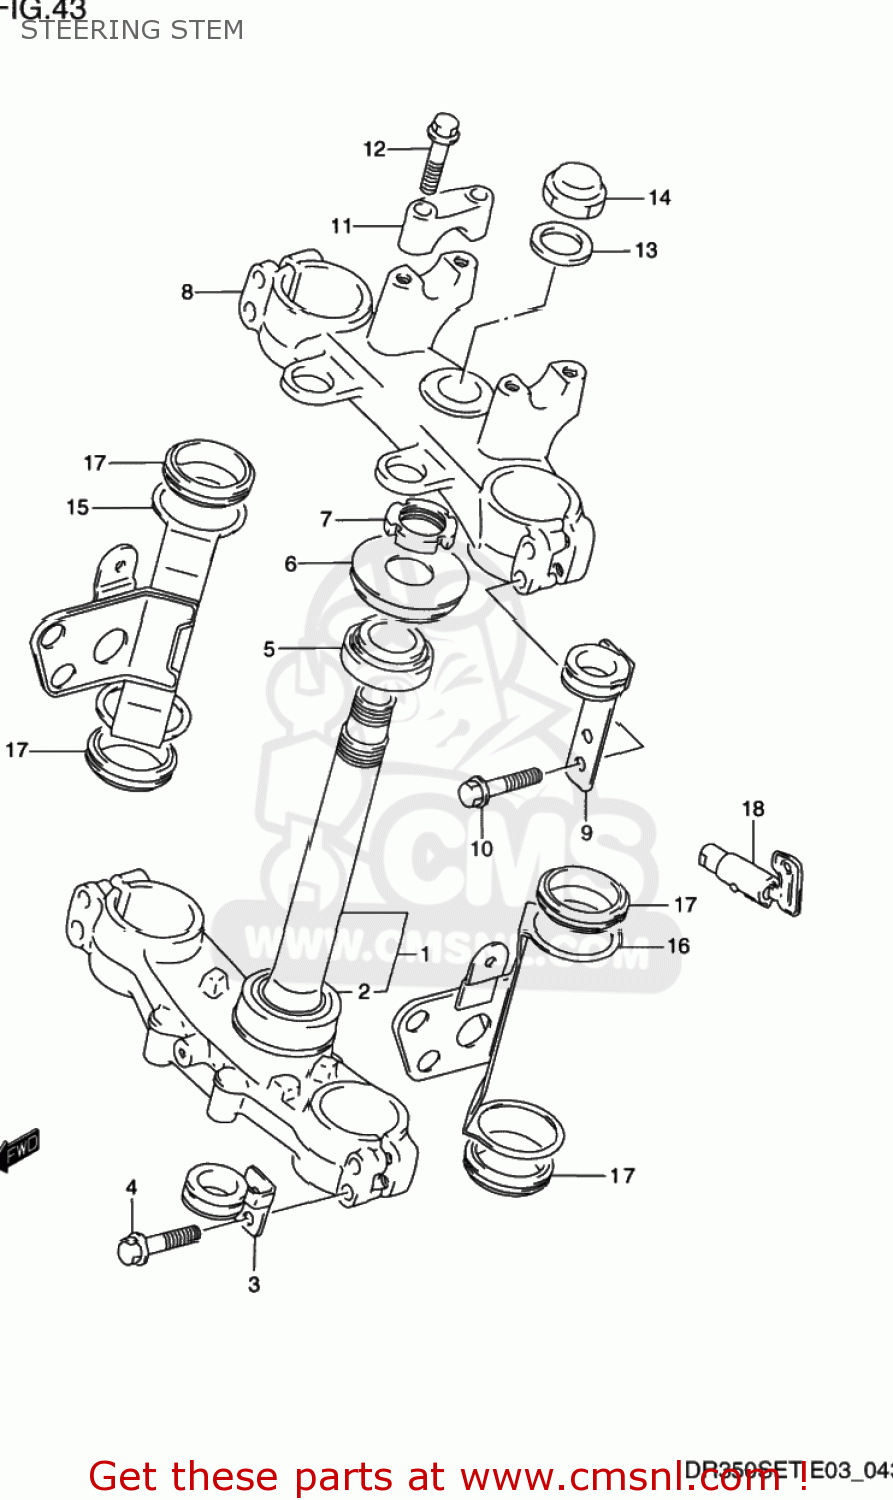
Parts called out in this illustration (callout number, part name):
1	STEM,STEERING
2	BEARING(30X55X17)
3	GUIDE,CABLE LWR,L
4	BOLT
5	TAPER,ROLLER BEARING
6	SEAL,STEERING UPR DUST
7	NUT,STEERING STEM
8	HEAD,STEERING STEM
9	GUIDE,CABLE,LEFT,UPPER
10	BOLT
11	HOLDER,HANDLE UPR
12	BOLT
13	WASHER
14	NUT,CAP
15	BRACKET,HEADLAMP HOUSING,R
16	BRACKET,HEADLAMP HOUSING,L
17	DAMPER,HEADLAMP HSG BRACKET
18	LOCK ASSY,STEERING(NEIMAN)
